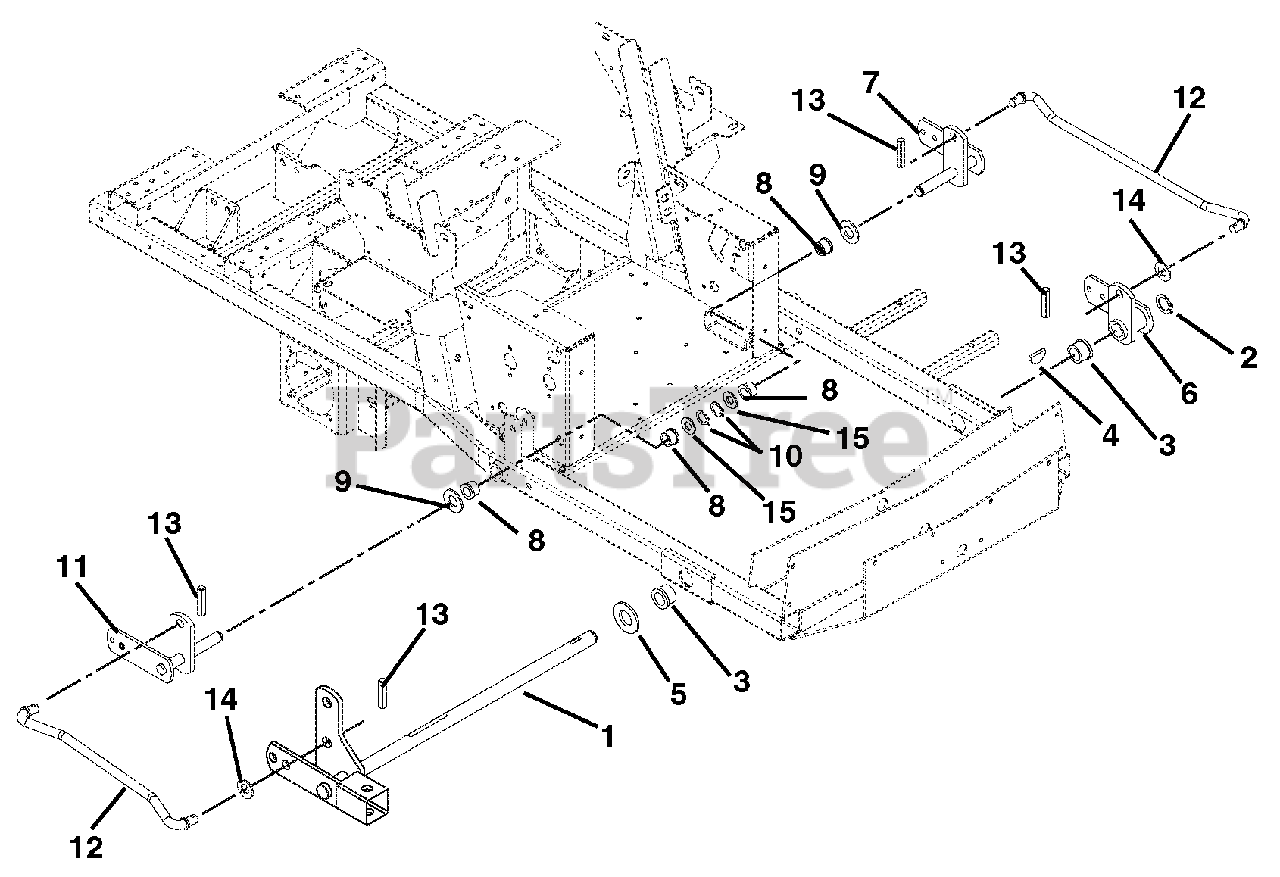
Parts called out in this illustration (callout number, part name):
1	Lift, Mower
2	Ring, Retaining External 1.00 x .078
3	Bushing, Flange Nylon 1.02 x 1.385 x .75 x 1.75
4	Key, Woodruff .25 x 1.00
5	Washer, Flat Steel 1.063 x 2.00 x .134
6	Weldment, Lift Arm-Front
7	Weldment, Rear Lift Arm-Left Hand
8	Bushing, Flange Nylon .762 x 1.0 x .58 x 1.48
9	Washer, Hardened Steel .758 x 1.23 x .031
10	Ring-Retaining-External .689 x .077
11	Weldment, Rear Lift Arm- Right Hand
12	Rod, Lift Assist 19.35"
13	Pin-Roll .250 x 1.25
14	Washer-Flat-Steel .656 x 1.31 x .095 YWZ
15	Washer-Flat-Steel .755 x 1.25 x .125
